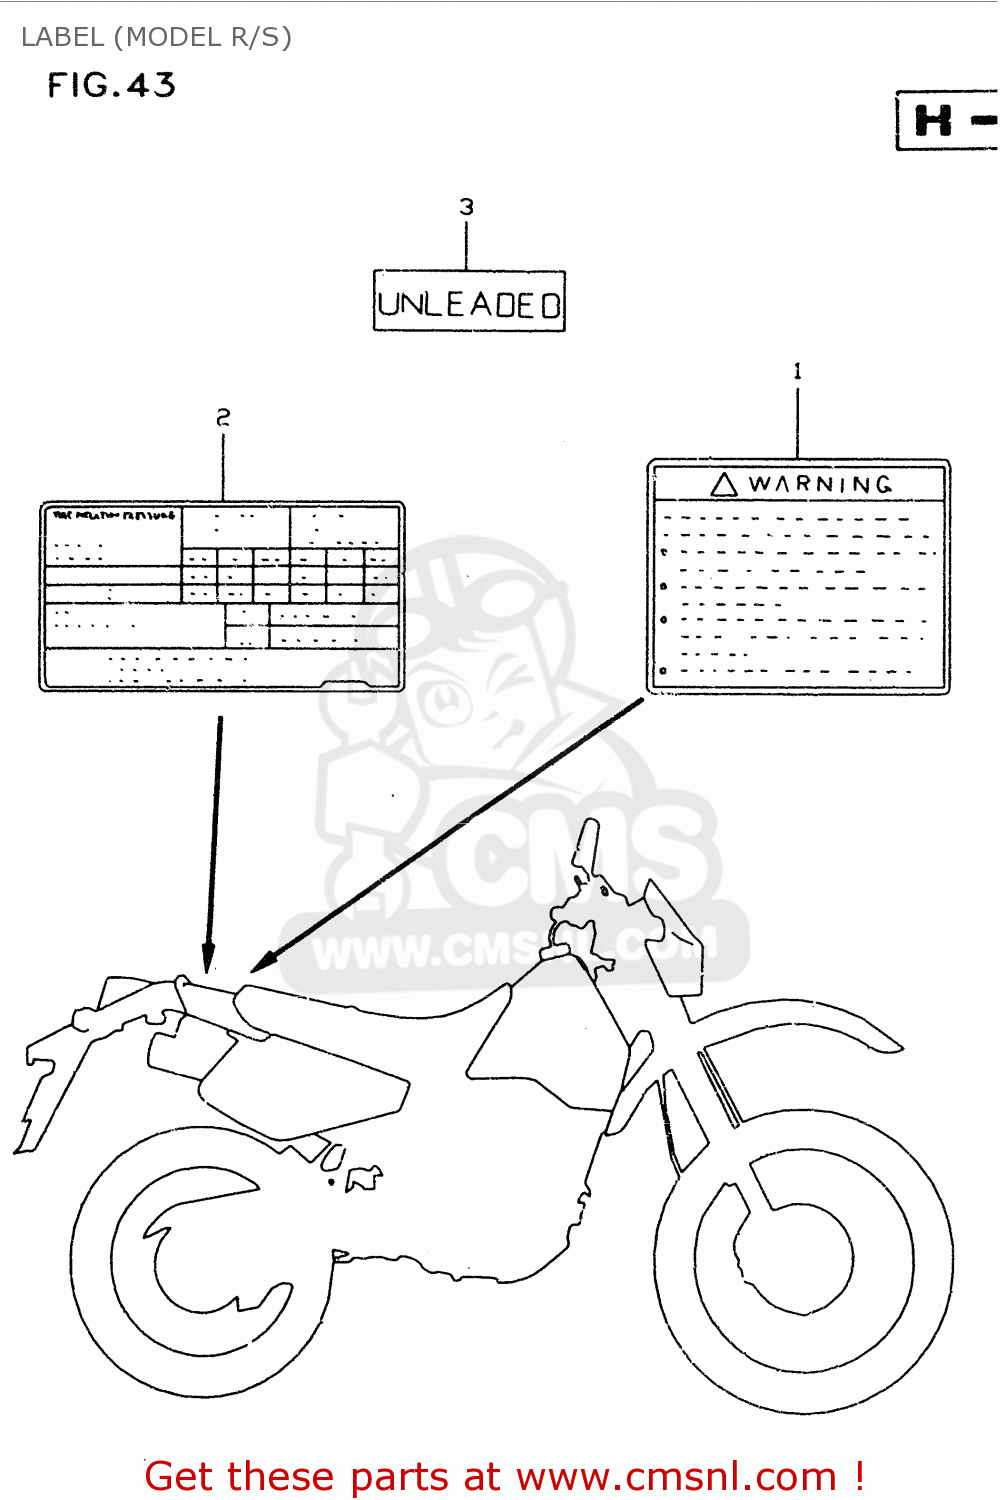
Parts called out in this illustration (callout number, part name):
1	LABEL, WARNING
2	LABEL, TIRE AIR PRESSURE
3	LABEL,CAUTION
4	MANUAL, OWNER'S
